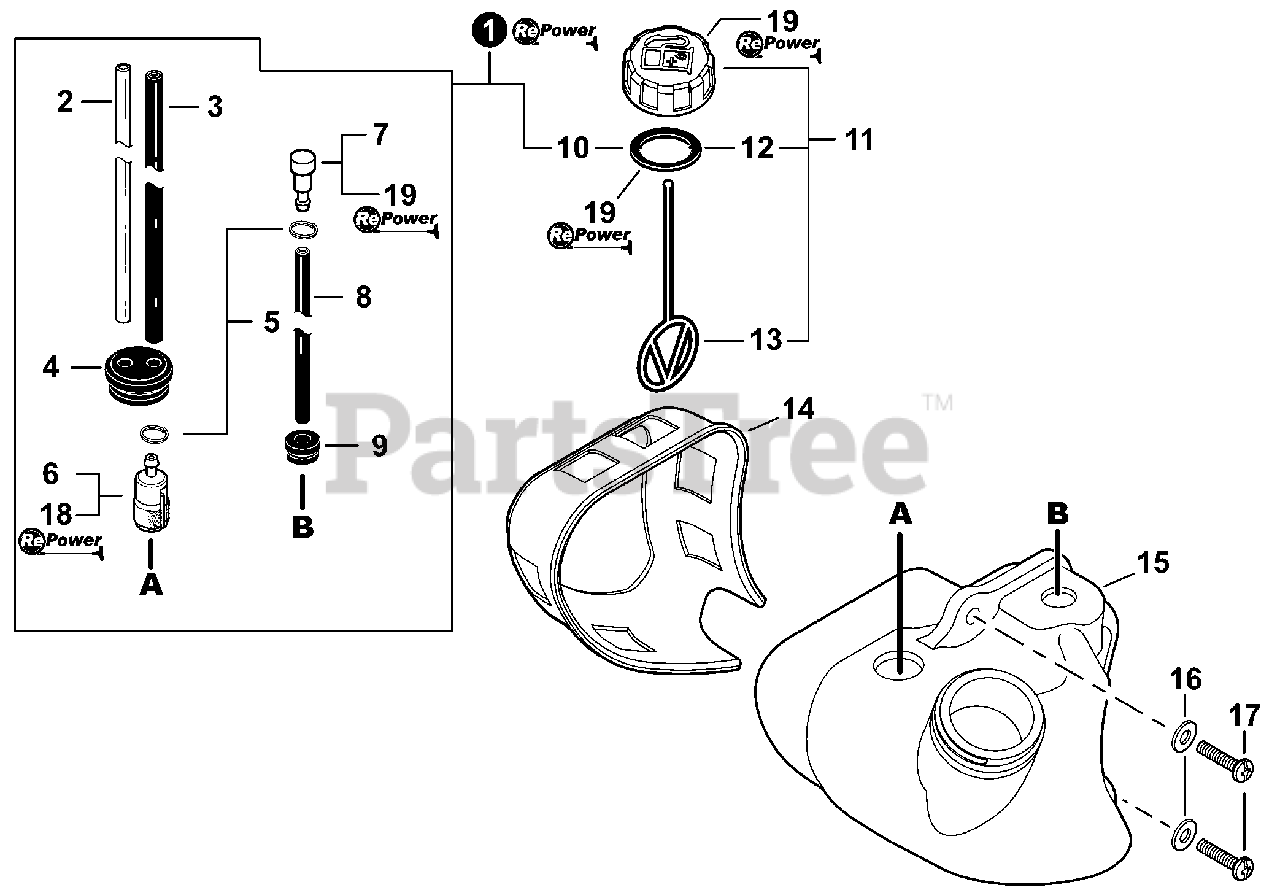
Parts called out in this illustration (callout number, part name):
1	FUEL SYSTEM KIT - REPOWER
2	PIPE, FUEL 3×6×85 CLEAR
4	GROMMET, FUEL
5	CLIP 6MM
6	FILTER, FUEL
7	VENT ASSY
8	PIPE, FUEL VENT 3×5×50
9	GROMMET
10	GASKET, FUEL CAP
11	CAP ASSY, FUEL
12	GASKET, FUEL CAP
13	CONNECTOR, CAP L= 100mm
14	GUARD, FUEL TANK
15	TANK, FUEL
16	WASHER 5.5×12×0.8
17	SCREW 5×20
18	TUNE-UP KIT - REPOWER
19	CAP/VENT KIT - REPOWER
